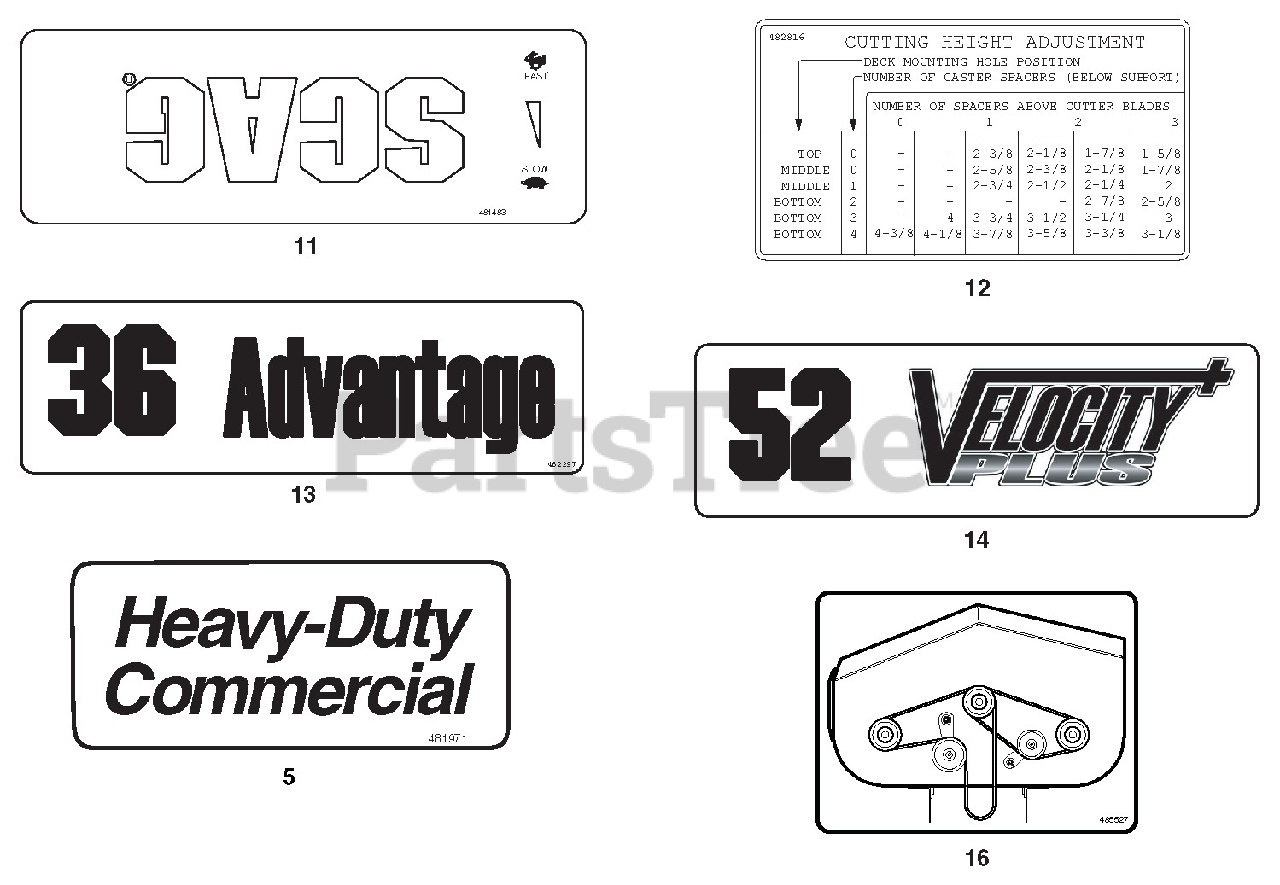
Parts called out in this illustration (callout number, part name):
5	Decal, Heavy Duty Commercial
11	Decal, Instrument Panel - Front
12	Decal, Height of Cut
13	Decal, 32
13	Decal, 36 Advantage
14	Decal, 48 Velocity Plus
14	Decal, 52 Velocity Plus
16	Decal, Belt Routing - 32 & 36A
16	Decal, Belt Routing - 48V & 52V
